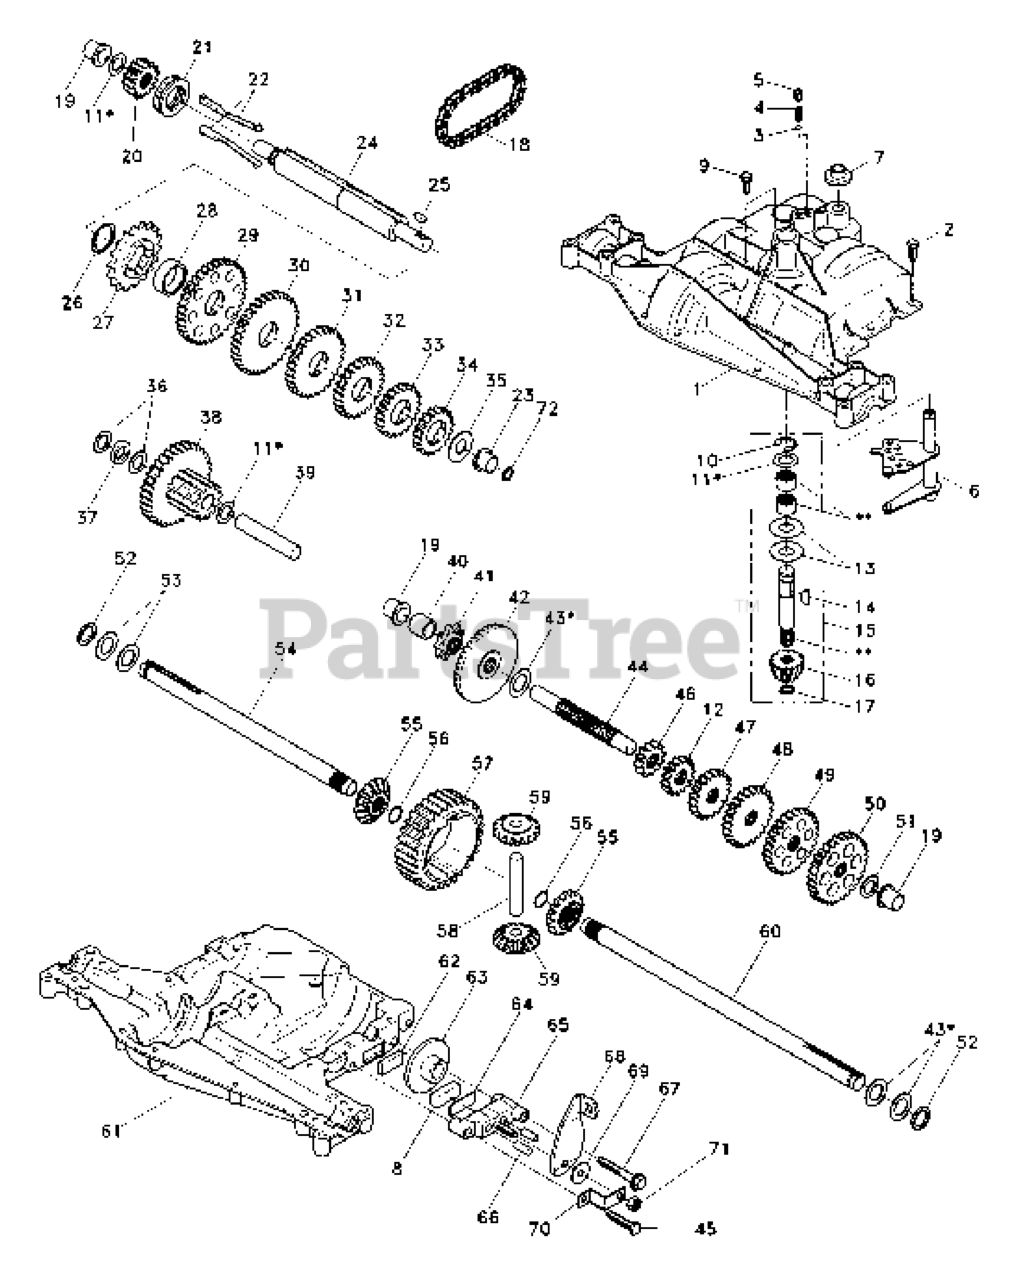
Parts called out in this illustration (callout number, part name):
1	HOUSING, UPPER
2	SCREW SELF TAPPING, LARGE
3	DETENT, BALL
4	SPRING, DETENT
5	SCREW, SET
6	SHIFTER KIT
7	BOOT, SHIFTER
8	PUCK, FRICTION
9	SCREW, SELF TAPPING W/SEALER
10	RING, RETAINING
11	SHIM.KIT.DANA.4689
12	GEAR SPUR 15T DANA
13	WASHER.PLAIN..632X1.38X.046
14	KEY.WOODRUFF.DANA
15	ASSY, KIT INPUT SHAFT
16	PIN, BEVEL, 14T YT
17	RING RETAINING
18	CHAIN 24 PITCH LT
19	BEARING, FLANGE LT
20	GEAR SPUR 14 TTH
21	COLLAR, CLUTCH
22	KIT ASM CLUTCH
23	BEARING.FLANGE.DANA
24	SHAFT INTERM DANA
25	KEY, WOODRUFF, #61
26	RING, RETAINING LT
27	SPROCKET 18T
29	GEAR, SPUR 37 TEETH
30	GEAR, SPUR 35 TEETH
31	GEAR, SPUR 30 TEETH
32	GEAR, SPUR 25 TEETH
33	GEAR, SPUR 22 TEETH
35	WASHER, PLAIN .640 X 1.37X.061
36	WASHER 025
38	ASSM GEAR COMB T NLA
39	SHAFT IDLER
40	SPACER, .635 X .875 X .755
41	SPROCKET 9T LT
42	GEAR, SPUR 42T YT
43	SHIM
44	SHAFT, DRIVE
45	SCREW, SELF TAPPING LARGE
46	GEAR SPUR 12 TEETH
47	GEAR, SPUR 20 TEETH
48	GEAR, SPUR 25 TEETH
49	GEAR, SPUR 28 TEETH
50	GEAR, SPUR 31 TEETH
51	WASHER, PLAIN .632 X1.00X.060
52	NEOPRENE.WASHER.DANA
53	WASHER, PLAIN .758 X 1.25X.031
54	AXLE T, LH
55	GEAR, MITER 15 TEETH
56	RING, RETAINING
58	SHAFT, CROSS
59	GEAR, MITER 15 TEETH
61	LOWER HOUSING
62	PUCK, FRICTION
63	BRAKE DISC T
65	JAW T
67	SCREW, SELF TAPPING, LARGE
68	LEVER ACTUATOR
69	WASHER, PLAIN .321 X 1.00X.055
70	BRACKET, ANTI ROTATION
71	LOCKNUT
73	SHELL, GREASE
